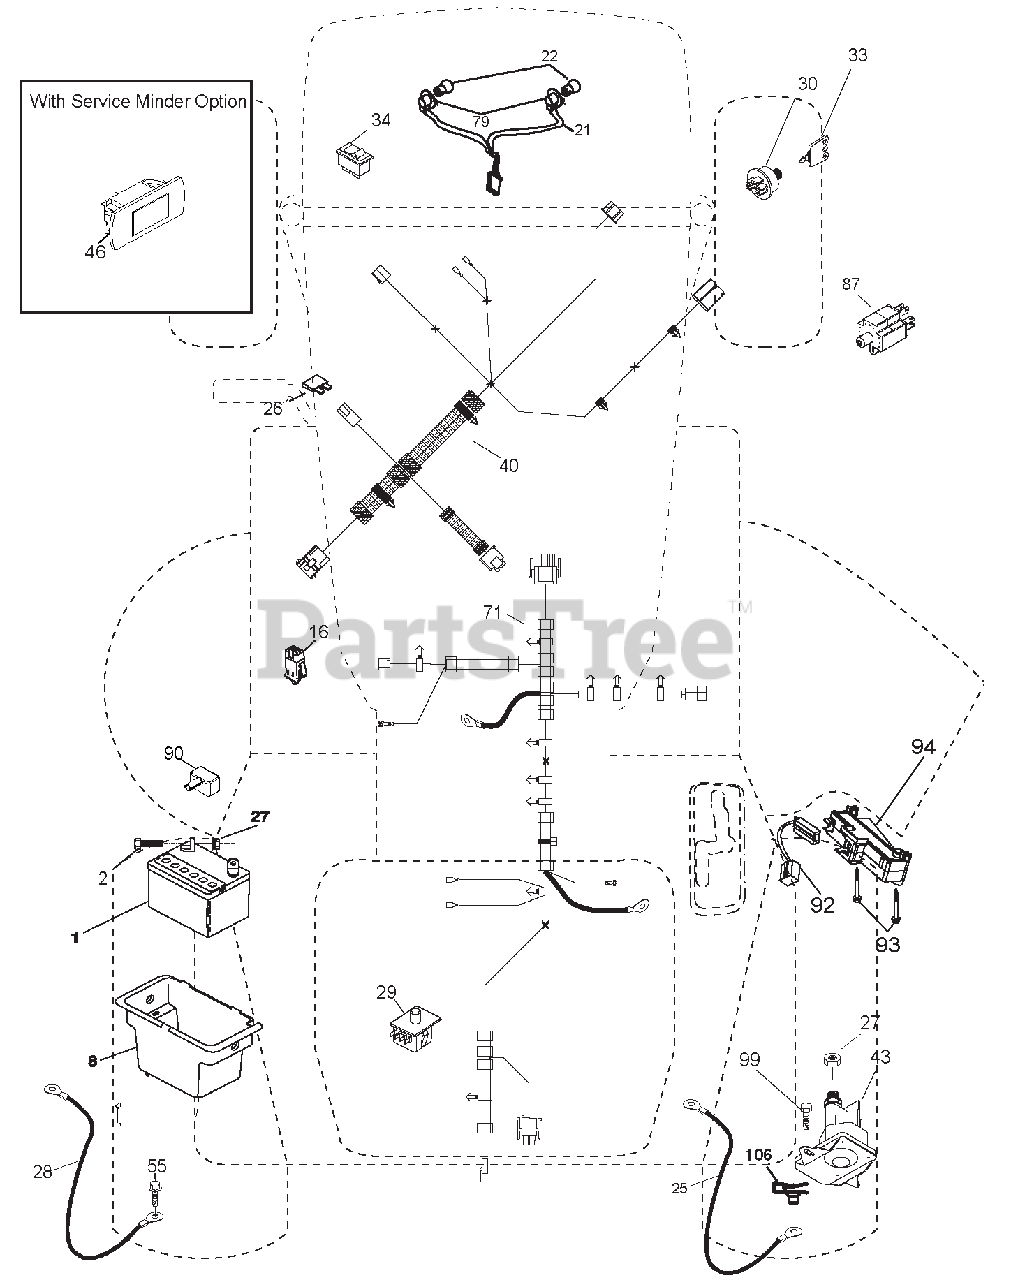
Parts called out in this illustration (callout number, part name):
1	BATTERY.12.VOLT.28.AMP.WET
2	BOLT.HEX.HD.1/4-20UNC X 3/4
8	BOX.BATTERY.MNT.REAR.LT.TEX.BL
16	SWITCH.INTERLOCK.NONO.GRAY
21	HARNESS ASM.LIGHT.22"(4152J)
22	BULB.LIGHT.#1156
25	CABLE STARTER 6 G4. BL/RED14.5
26	FUSE.20 AMP.
27	Nut, Keps Hex 1/4-20 unc
28	CABLE.BLACK.22"REAR BATT.TEX
29	SWITCH.SEAT.DELTA.OPC.9LB.
30	SWITCH.IGN.DLTA.P-IN.ROS
33	KEY/CHAIN.BLISTER PACK.GEN.USA
34	SWITCH.LIGHT/RESET.B/B/RED.
40	HARNESS IGN ELEC RELAY
43	SOLENOID.W/BRASS PLUNGER.2005
46	HOUR METER
50	SWITCH.PTO.8 TERMINAL.BLACK
55	SCREW.5/16-18X3/4.SMGML.TAP/R
71	HARNESS.IGN.CHASSIS.TEX
79	SOCKET ASM.BULB.TWISTLOCK
90	COVER TERMINAL BATTERY FR. TEX
92	HARNESS.PIGTAIL.CONSLE.ROS.MLK
93	SCREW.PLASTITE.10-14 X 2.0
94	MODUAL REVERSE ROS
